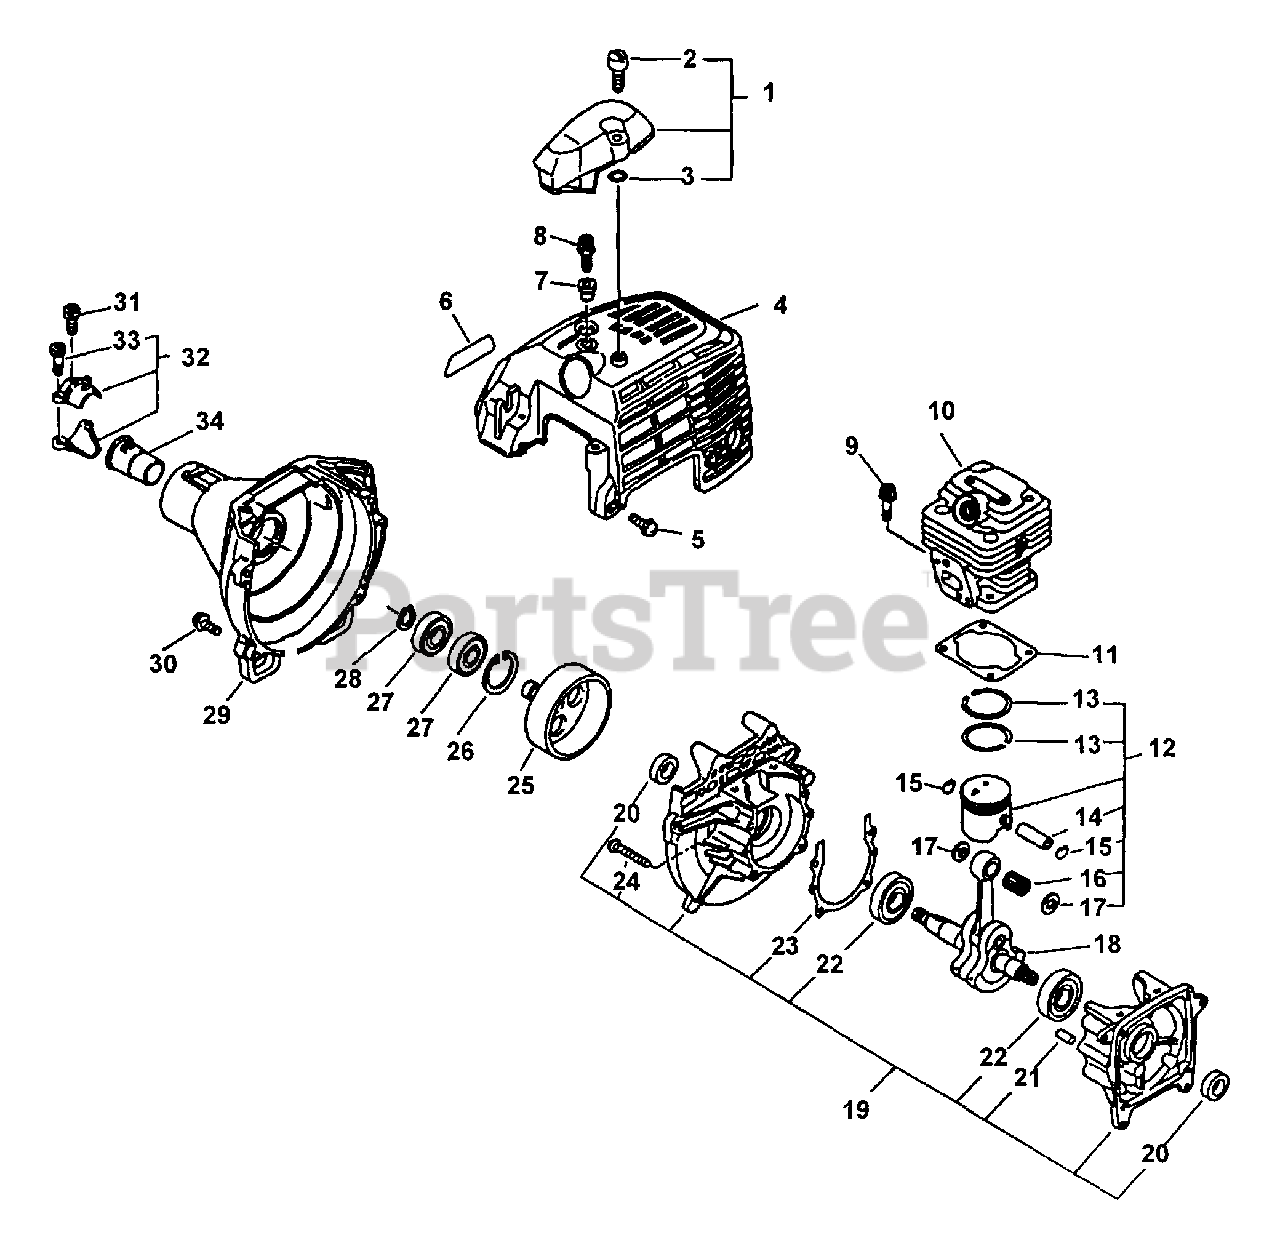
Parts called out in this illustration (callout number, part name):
1	GUARD KIT, TOP
2	THUMBSCREW M5×15.5
4	COVER, ENGINE
5	BOLT 5×12
6	LABEL, MODEL
6	LABEL - MODEL SRM-3110
8	BOLT 5×20
9	BOLT 5×20
10	CYLINDER
11	GASKET, CYLINDER
12	PISTON KIT
13	RING, PISTON
14	PIN, PISTON
15	RING, RETAINING
16	BEARING, NEEDLE 9
17	WASHER, THRUST
18	CRANKSHAFT ASSY
19	CRANKCASE KIT
20	SEAL, OIL 12
21	PIN, LOCATING 4
22	BEARING, BALL - 6201 C3
23	GASKET, CRANKCASE
24	BOLT 5×30
25	DRUM, CLUTCH
26	RING, SNAP 28
27	BEARING, BALL 6001
28	RING, RETAINING - 12
29	COVER, FAN
30	BOLT 5×20
31	BOLT 5×12
32	RETAINER KIT
33	BOLT 5×25
